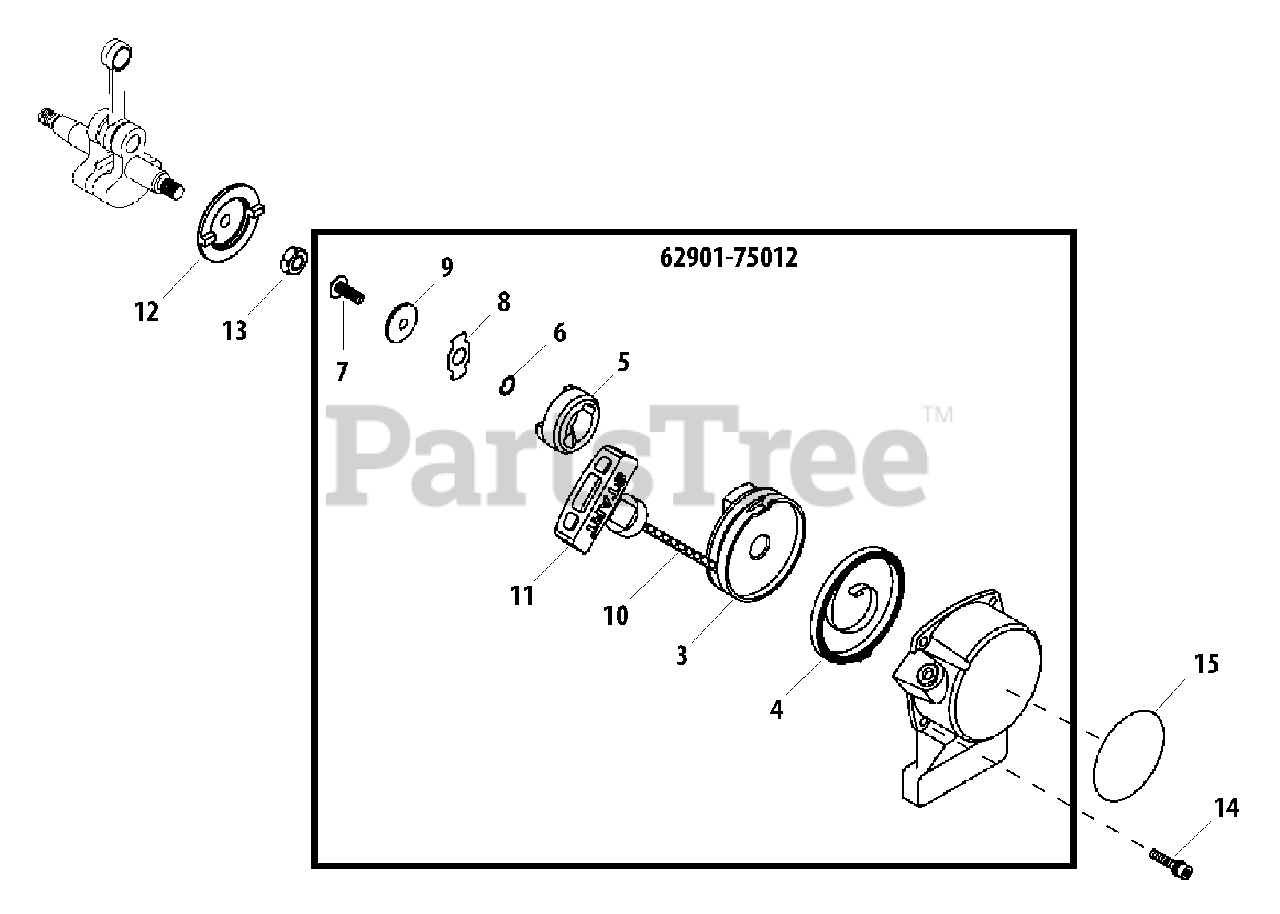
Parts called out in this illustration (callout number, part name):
3	REEL, ROPE
4	SPRING, REWIND
5	PAWL, STARTER
6	WASHER - SPRING
7	SCREW - 5
8	RETAINER
9	WASHER - 5
10	ROPE, STARTER
11	GRIP, STARTER
12	PAWL
13	NUT - 8
14	SCREW - 4X16
15	LABEL - C4
62901-75012	STARTER ASSY
